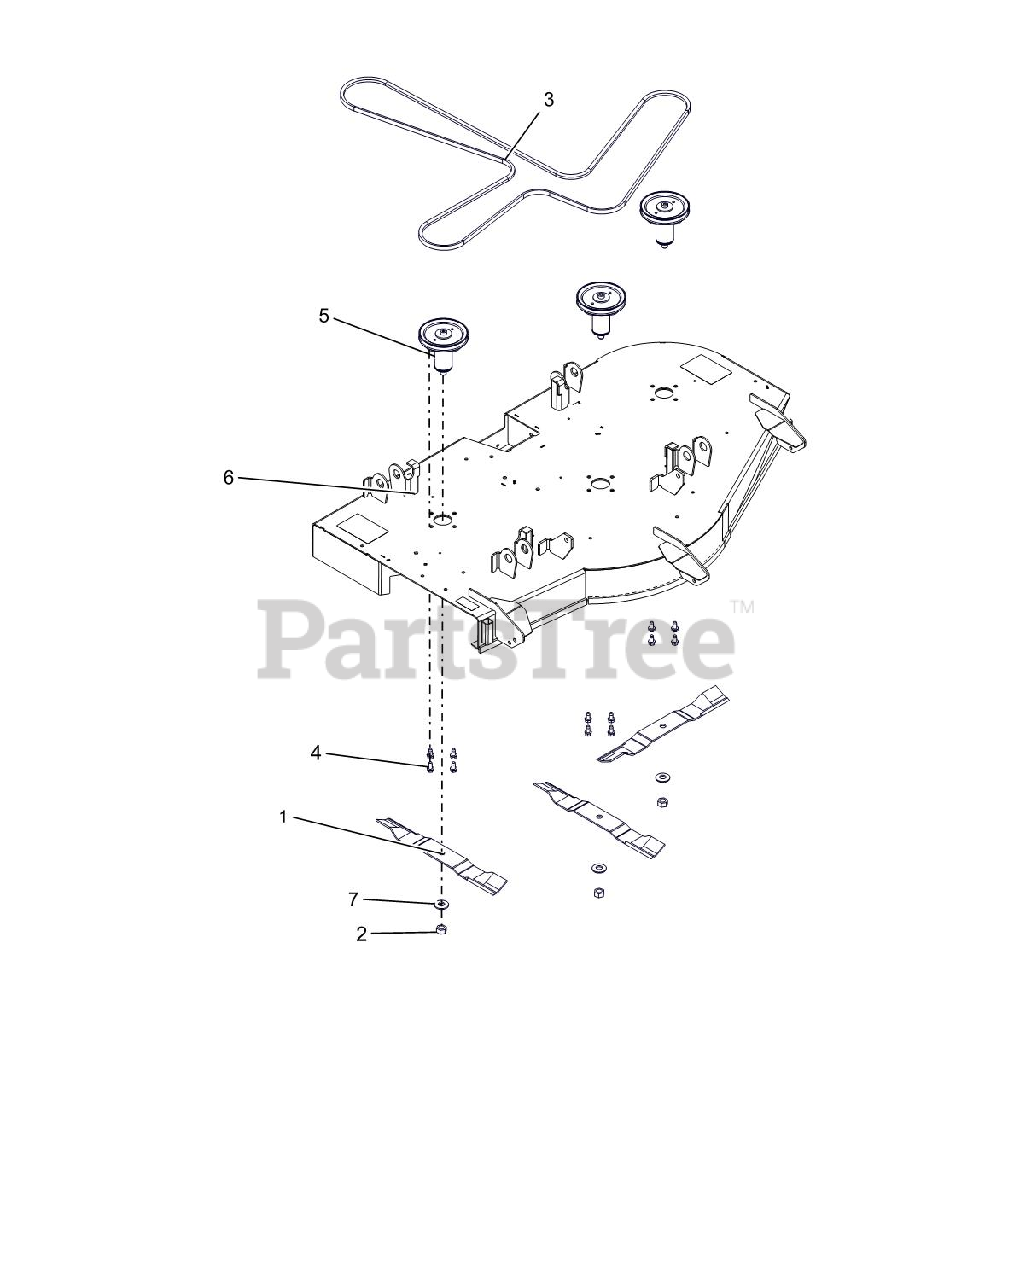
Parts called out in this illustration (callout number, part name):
1	BLADE, 18" - 30 DEG .5 OFFSET
2	NUT-HEX .62-18 YWZC
3	V-BELT, HA-WRAPPED
4	@SCR-TAP .38-16X.75 HWH TR YWZ
5	KIT, DECK SPINDLE ASM-52
6	KIT, 52" GRAVELY DECK W/DECALS
7	WSHR-BLVL .669X1.535X.138
